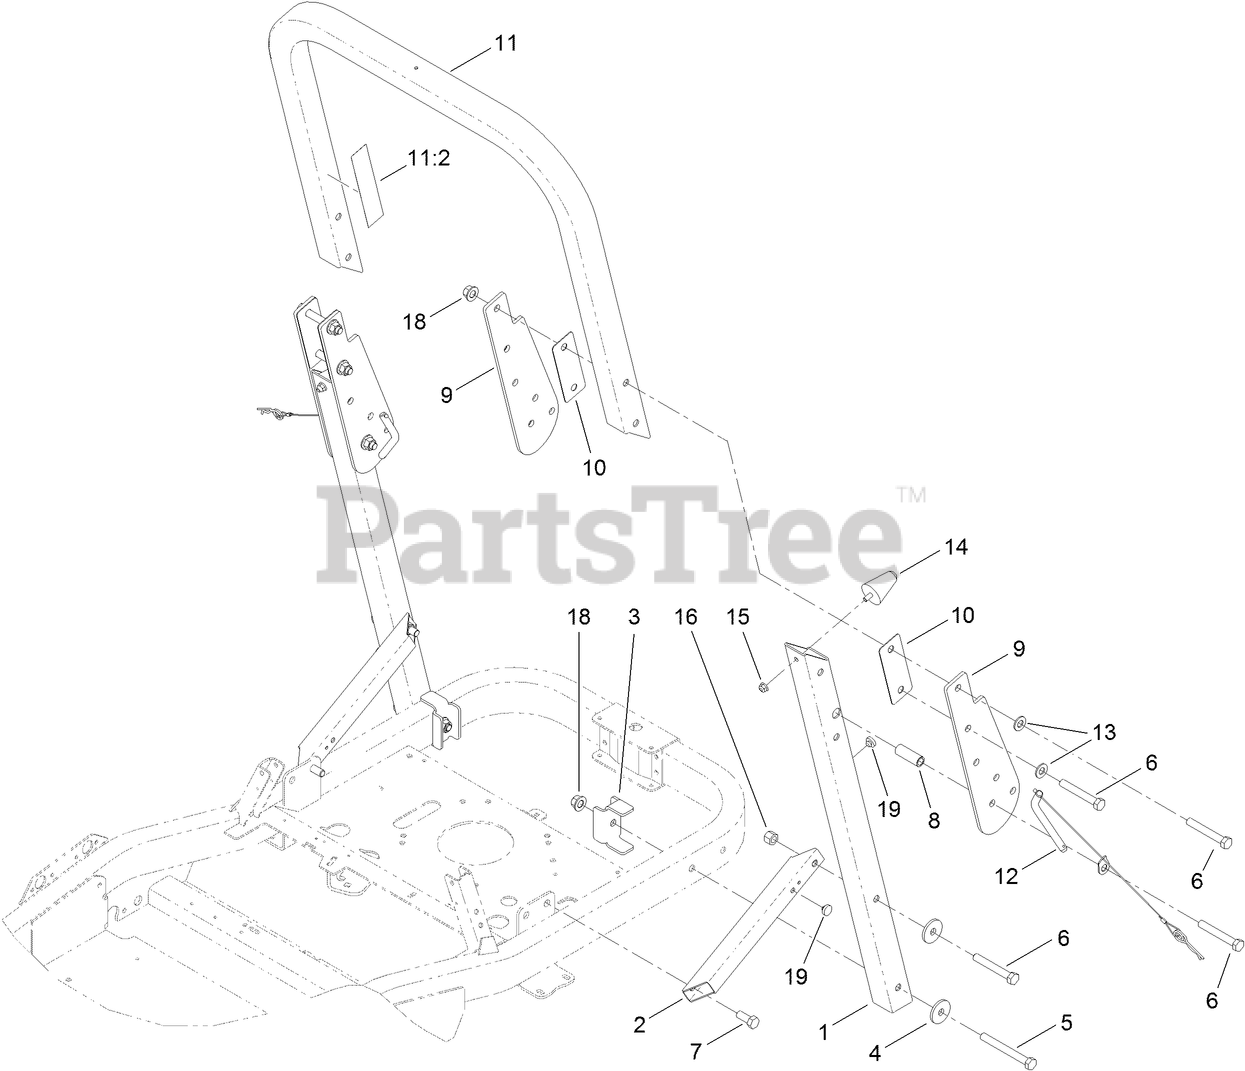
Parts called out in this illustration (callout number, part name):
1	TUBE-ROPS, LOWER
2	TUBE-SUPPORT, ROPS
3	BRACKET-REINFORCING
4	WASHER-THRUST
5	SCREW-HH
6	SCREW-HH
7	SCREW-HH
8	SPACER
9	BRACKET-PIVOT, ROPS
10	SPACER-ROPS
11	UPPER ROPS ASM
11:2	DECAL-WARNING
12	PIN-ROPS W/ LANYARD
13	WASHER-FLAT
14	BUMPER-RUBBER
15	NUT-HF, NI
16	NUT-HEX
18	NUT-LOCK
19	BUMPER
